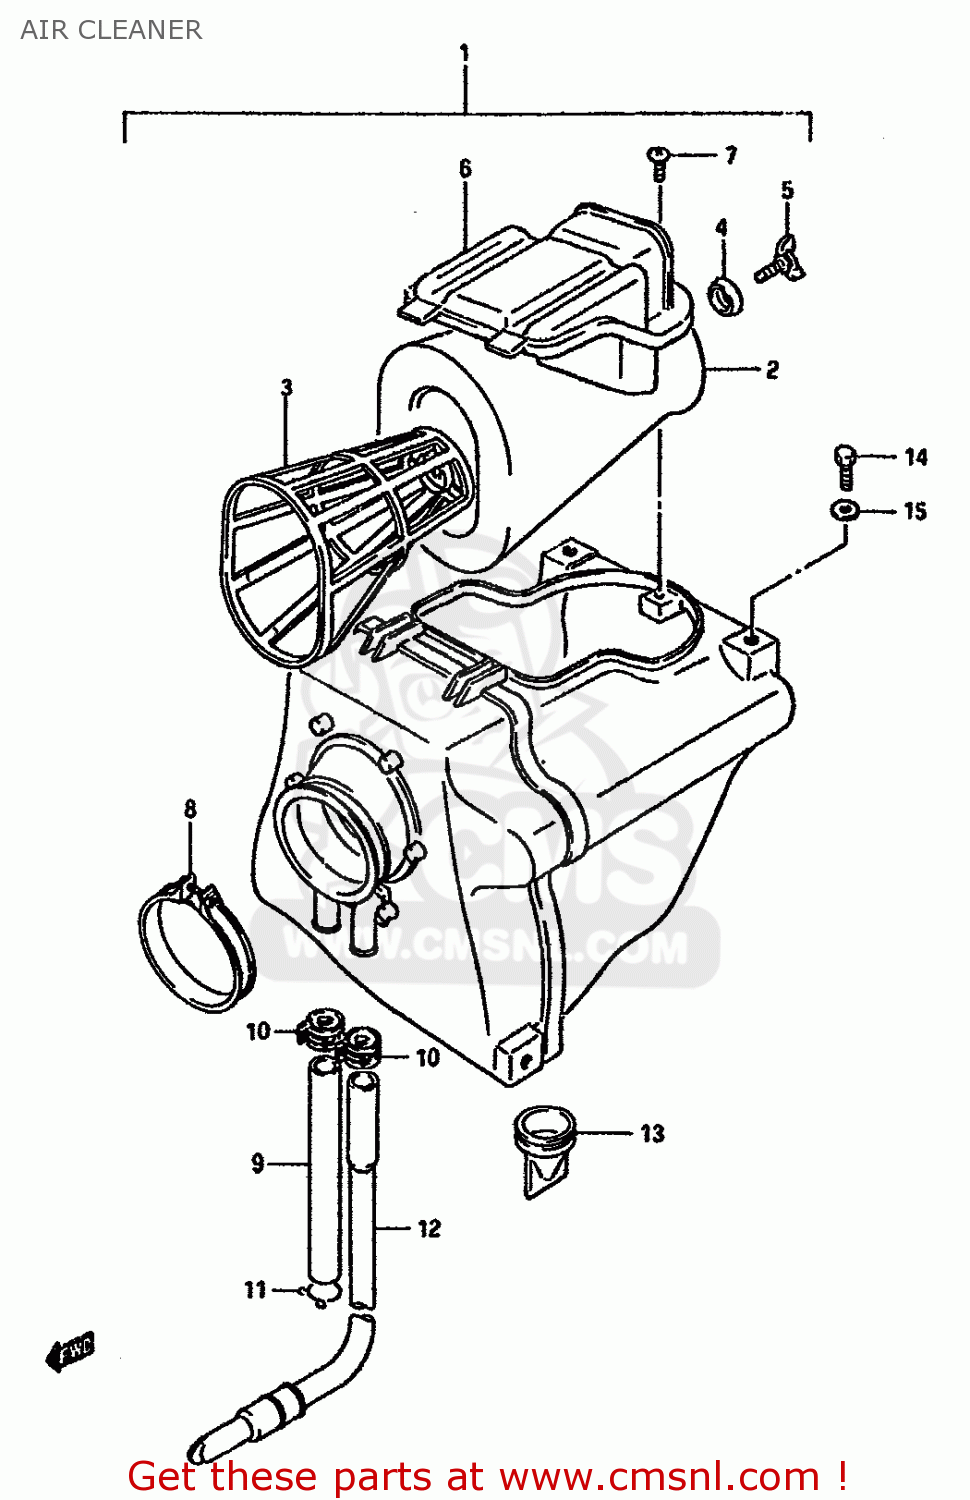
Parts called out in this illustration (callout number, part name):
1	CLEANER ASSY,AIR
2	FILTER,AIR CLEANER
3	HOLDER
4	WASHER,FILTER HOLDER
5	BOLT,AIR CLEANER
6	CAP,AIR CLEANER
7	SCREW
8	CLAMP
9	TUBE,BREATHER
10	CLIP
11	CLIP
12	DRAIN TUBE
13	HOSE,AIR CLEANER DRAIN
14	BOLT(6X14)
15	WASHER
